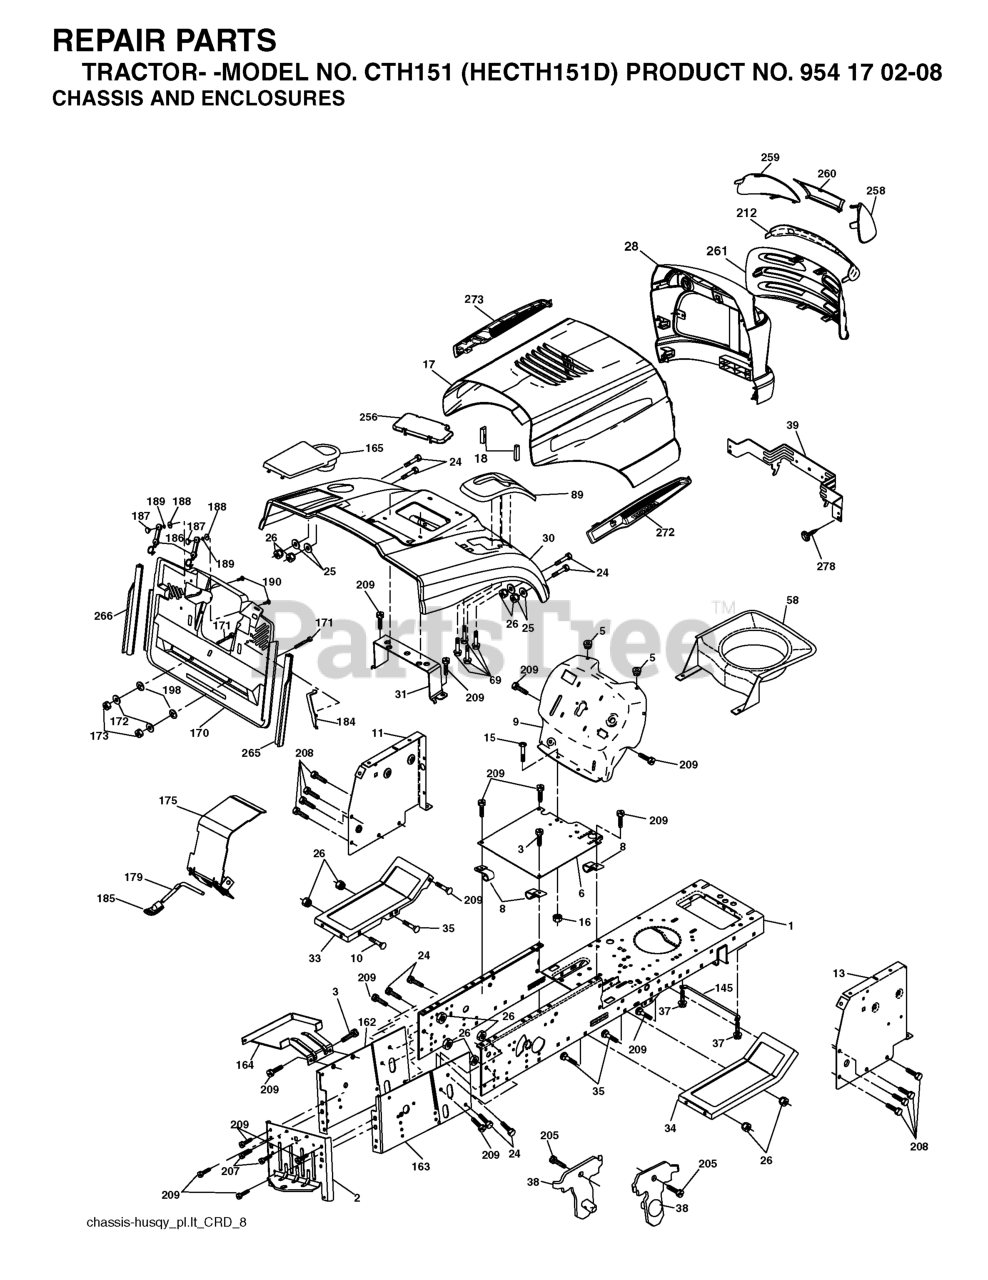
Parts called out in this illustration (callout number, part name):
2	DRAWBAR
3	SCREW 3/8-16X3/4
5	BUMPER.RUBBER.HOOD
6	PLATE
8	CLIP,INSULATOR
10	BOLT D
11	PANEL.DASH.LH.LTX
13	PANEL ASM, DASH RH
15	Screw, Machine, Truss Head 5/16-18 UNC x 3/4
16	NUT
17	VENT.HOOD.LASER.III
18	BUMPER.HOOD.LARGE.1.75"
25	WASHER
26	NUT
31	BRACKET SUPPORT FENDER
33	FOOTREST PNT LH
34	FOOTREST PNT RH
37	Screw 5/16-18 x 1/2 Hex, Self Tapping 5/16-18 x 1/2
38	BRACKET ASM PIVOT MOWER REAR
39	BRACKET PIVOT LASER
69	SCREW.HI-LO.CONSOLE
89	HOOD.PNT.STEEL.LASER.LT
145	ROD PIVOT CHASSIS/HOOD
162	BRACKET
163	BRACKET EXTEN CHASSIS RH CRD
165	RP.COVER.BATTERY.CRD.GREY
172	WASHER
175	DOOR TRAP
179	ROD PIVOT FBI
184	BRACKET.ACTUATOR.BAGGER.SRD
186	LATCH ASSY
187	WELDNUT
189	LOCKWASHER #10
190	SCREW
207	SCREW, 5/16-18 X 1/2
208	SCREW 3/8-16X1/2
209	SCREW, 3/8-16X3/4
212	INSERT.LENS.REFLECTIVE
256	COVER FENDER CRD
258	LENS LH
259	LENS LH
260	COVER.LENS.HUSQ.LASER
265	SEALING
266	SEALING
272	VENT.HOOD.LASER.
273	VENT.HOOD.LASER.
278	SCREW
